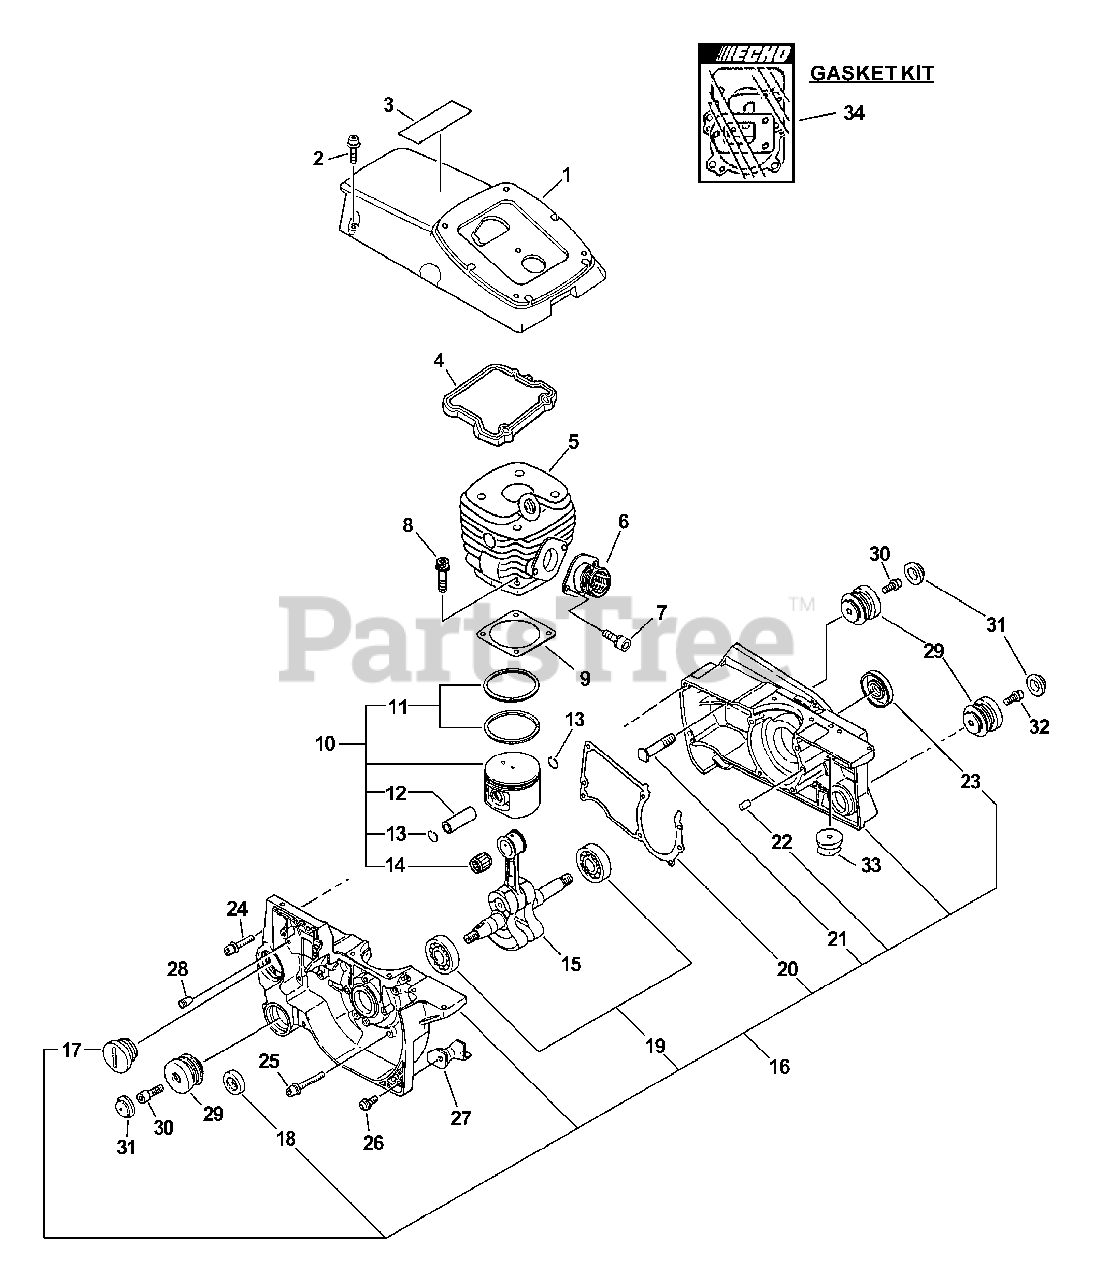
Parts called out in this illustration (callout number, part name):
1	COVER, ENGINE
2	BOLT 5×20
3	LABEL, CAUTION
4	CUSHION
5	CYLINDER
6	BELLOWS, INTAKE
7	BOLT 4×14
8	BOLT 5×25
9	GASKET, CYLINDER
10	PISTON KIT
11	RING, PISTON
12	PIN, PISTON 12
13	RING, SNAP
14	BEARING, NEEDLE
15	CRANKSHAFT ASSY
16	CRANKCASE KIT
17	CAP, OIL TANK
18	SEAL, OIL
19	BEARING, BALL 6202
20	GASKET, CRANKCASE
21	STUD, GUIDE BAR
22	PIN, LOCATING 5×10
23	SEAL, OIL
24	BOLT 5×20
25	BOLT M5×35
26	SCREW 5×14
28	VENT ASSY
31	CAP, CUSHION
32	BOLT 5×14
34	GASKET KIT
